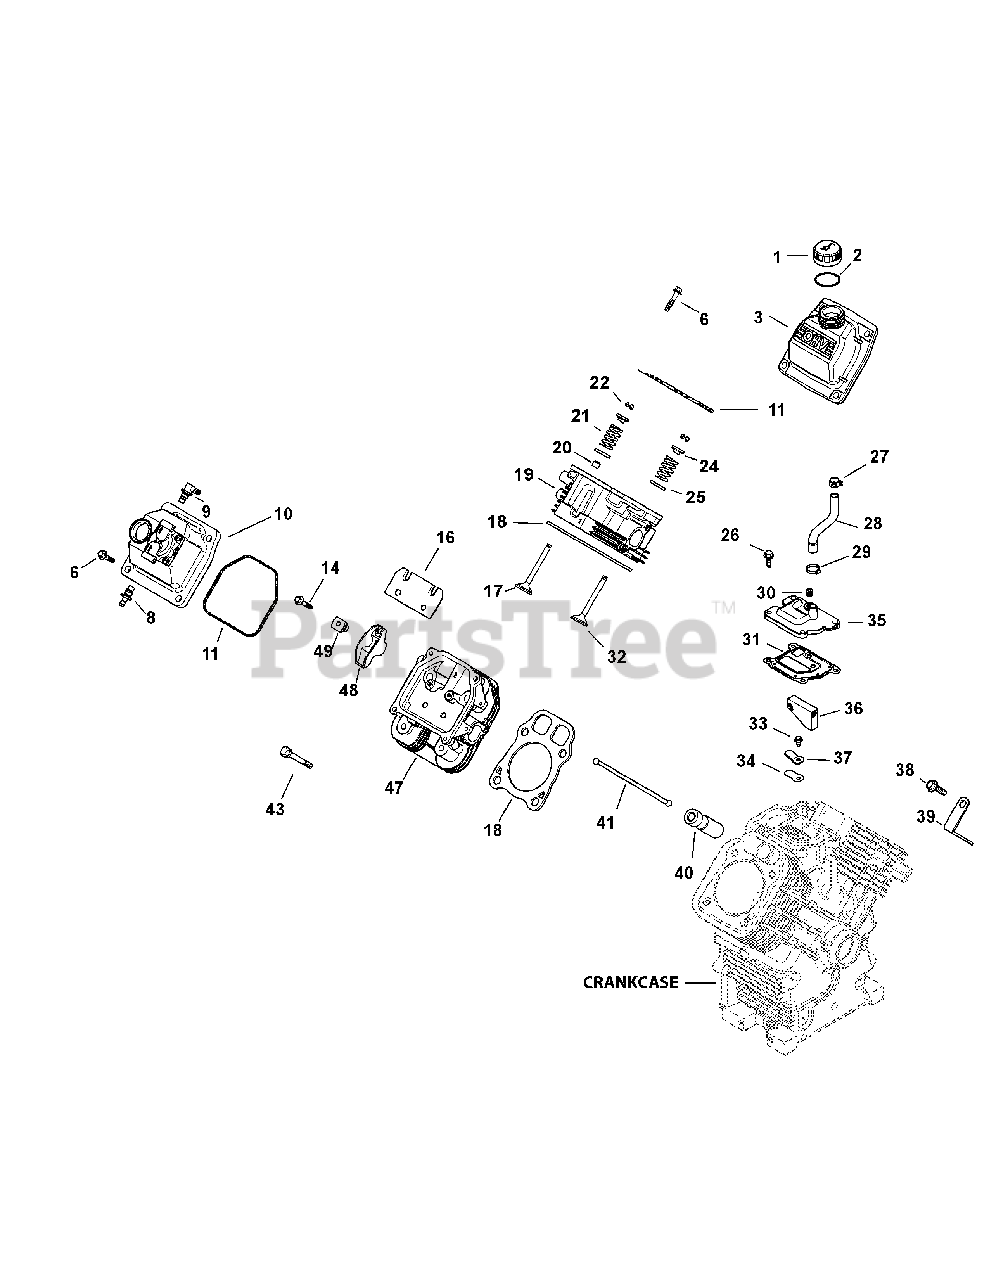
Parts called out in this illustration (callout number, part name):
1	Kit, Oil Fill Cap (Yellow)
2	O-Ring, Dipstick
3	Kit, Valve Cover-Oil Fill
6	Screw, Flg M6X1.0X30
8	Kit, 1/4" Fitting (Straight)
9	Kit, 90 Deg. Fitting
10	Kit, Valve Cover-Fuel Pump
11	O-Ring (Yellow), Valve Cover
14	Screw, Flg M6X1.0X34
16	Kit, Valve Train
17	Valve, Exhaust (Std)
17	Valve, Exhaust (.25)
18	Kit, Cyl Head Gasket (C17-22)
19	Kit, #1 Cyl Head Assy
20	Seal, Valve Stem
21	Spring, Valve
22	Kit, Retainer
24	Cap, Valve Spring
25	Retainer, Spring
26	Screw, Thread Forming
27	Clamp, Band Spring Hose
28	Hose, Breather
30	Plug, Ctsk Pipe 1/8"
31	Gasket, Breather
32	Valve, Intake (Std)
32	Valve, Intake (.25)
33	Screw, Flg Thd Frm M5X.8X10
34	Reed, Breather
35	Kit, Breather Assy
36	Filter, Breather
37	Retainer, Reed
38	Screw, Thread Forming
40	Hydraulic Valve Lifter
43	Screw, Flg M10X1.5X90
47	Kit, #2 Cyl Head Assy
49	Pivot, Rocker Arm
